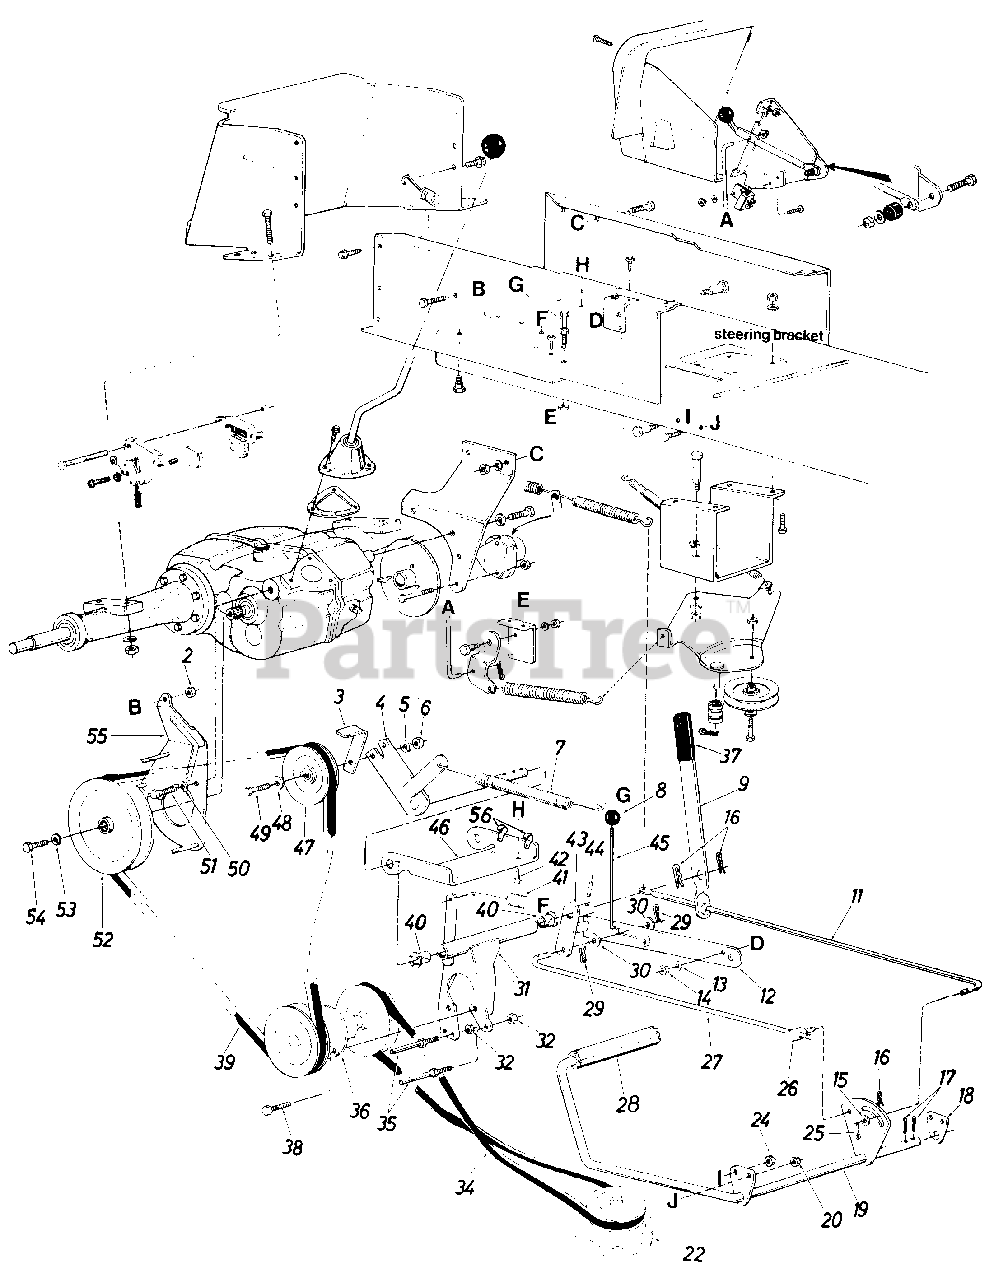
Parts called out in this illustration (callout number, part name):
2	Hex L-Nut 3/8-16 Thd.
5	L-Wash. 3/8" I.D.
6	Hex Nut 3/8-16 Thd.
7	Ext. Spring
8	Knob
9	Hand Brake Lever
11	Brake Rod
12	Parking Brake Cam
13	L-Wash. 5/16" I.D.
14	Hex Nut 5/16-18 Thd.
15	Fl-Wash. 5/16" I.D.
16	Hairpin Cotter 3/8" Rod
17	Cotter Pin 1/8" Dia. x 1.00" Lg.*
18	Clutch Rod Brg. Brkt.
19	Clutch-Brake Pedal Ass'y.
20	Hex Cent. L-Nut 3/8-16 Thd.*
22	Engine Pulley 4.75 & 5.56
24	Hex Cent. L-Nut 3/8-16 Thd.
25	Cotter Pin 3/32" Dia. x .75" Lg.
26	Pivot Bushing
27	Brake Cam Rod
28	Foot Pad
29	Hairpin Cotter 3/8" Rod
30	Fl-Wash. 3/8" I.D. x 1.00" O.D. x .030
31	Jack Shaft Mtg. Brkt. Ass'y.
32	Hex Top L-Nut 3/8-16 Thd.
34	"V"-Belt
35	Stud 3/8-16 x 3.62" Lg. Special
36	Jack Shaft Ass'y.
37	Flat Grip
38	Hex Sem Scr. 5/16-18 x .75" Lg.*
39	"V"-Belt
40	Nyliner 5/8" I.D. x .88" Lg.
41	Ext. Spring
42	Hex Thd. Rolling Scr. 1/4-20 x .50" Lg.
43	Clutch-Idler Horn Ass'y.
44	Spring Pin Spiral 1/4" Dia. x 1.00" Lg.
45	Parking Brake Link
46	Idler Mtg. Brkt.-Drive
47	4" "V"-Idler Pulley
48	Fl-Wash. 3/8" I.D.
49	Hex Bolt 3/8-16 x 1.75" Lg.
50	L-Wash. 3/8" I.D.
51	Hex Bolt 3/8-16 x .75" Lg.
52	"V"-Pulley 7.0" O.D.
53	L-Wash. 3/8" I.D.
54	Hex Scr. 3/8-24 x .75" Lg.
55	Belt Guard Ass'y.
56	Plastic Hose Clamp
